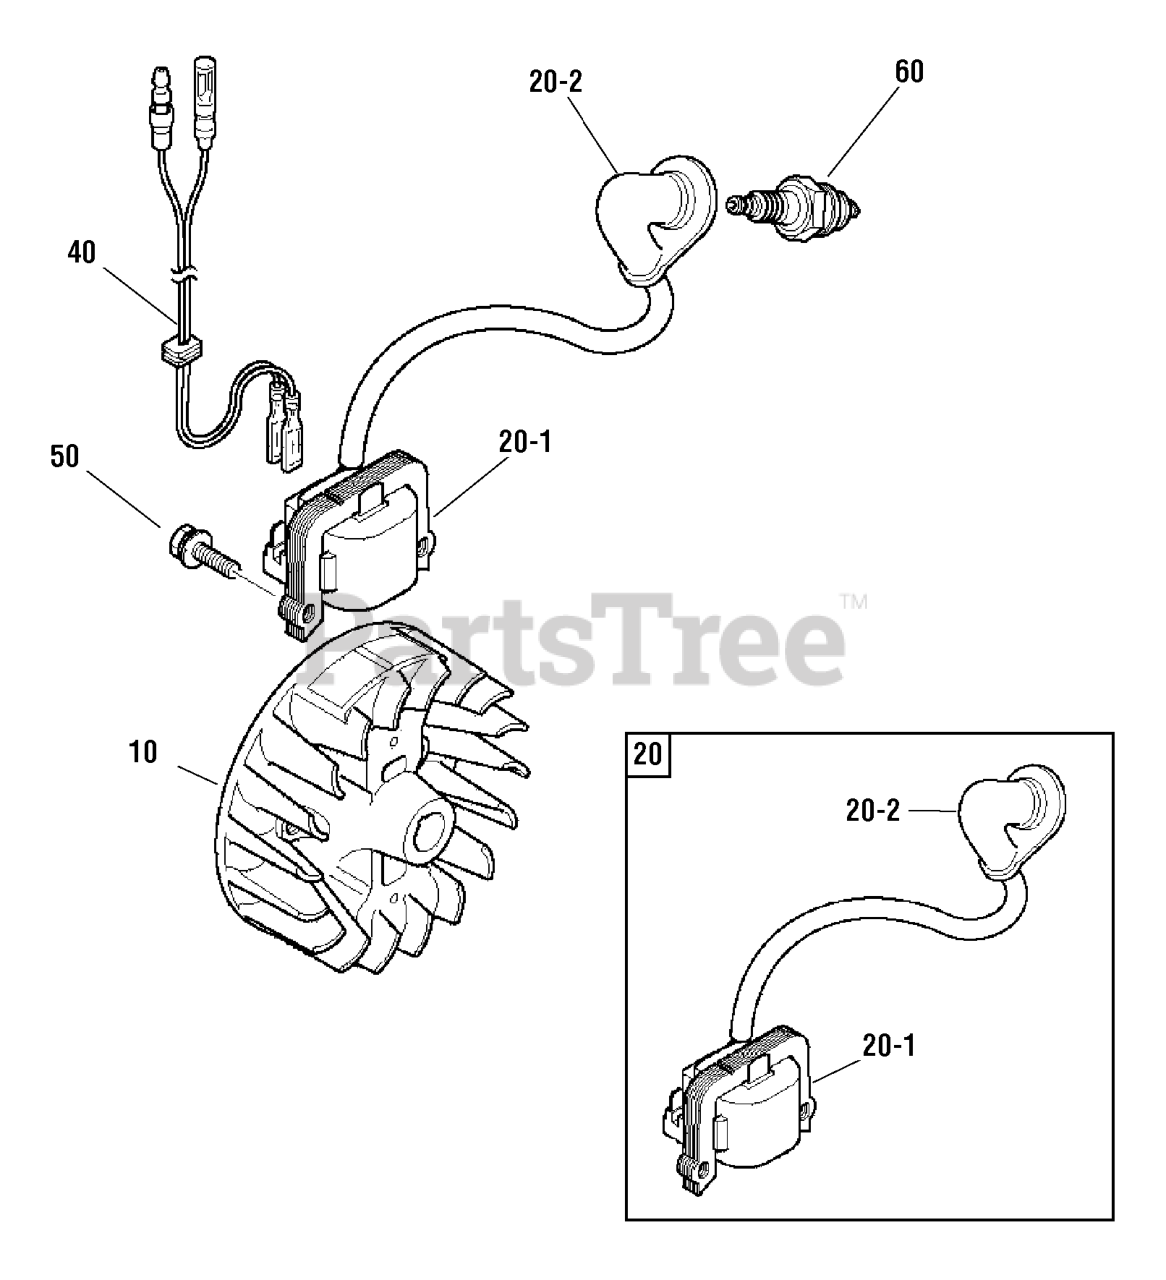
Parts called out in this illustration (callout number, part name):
20	COIL ASSEMBLY
20-1	COIL, Ignition
20-2	CAP, Plug
40	WIRE, Lead
50	BOLT & WASHER
